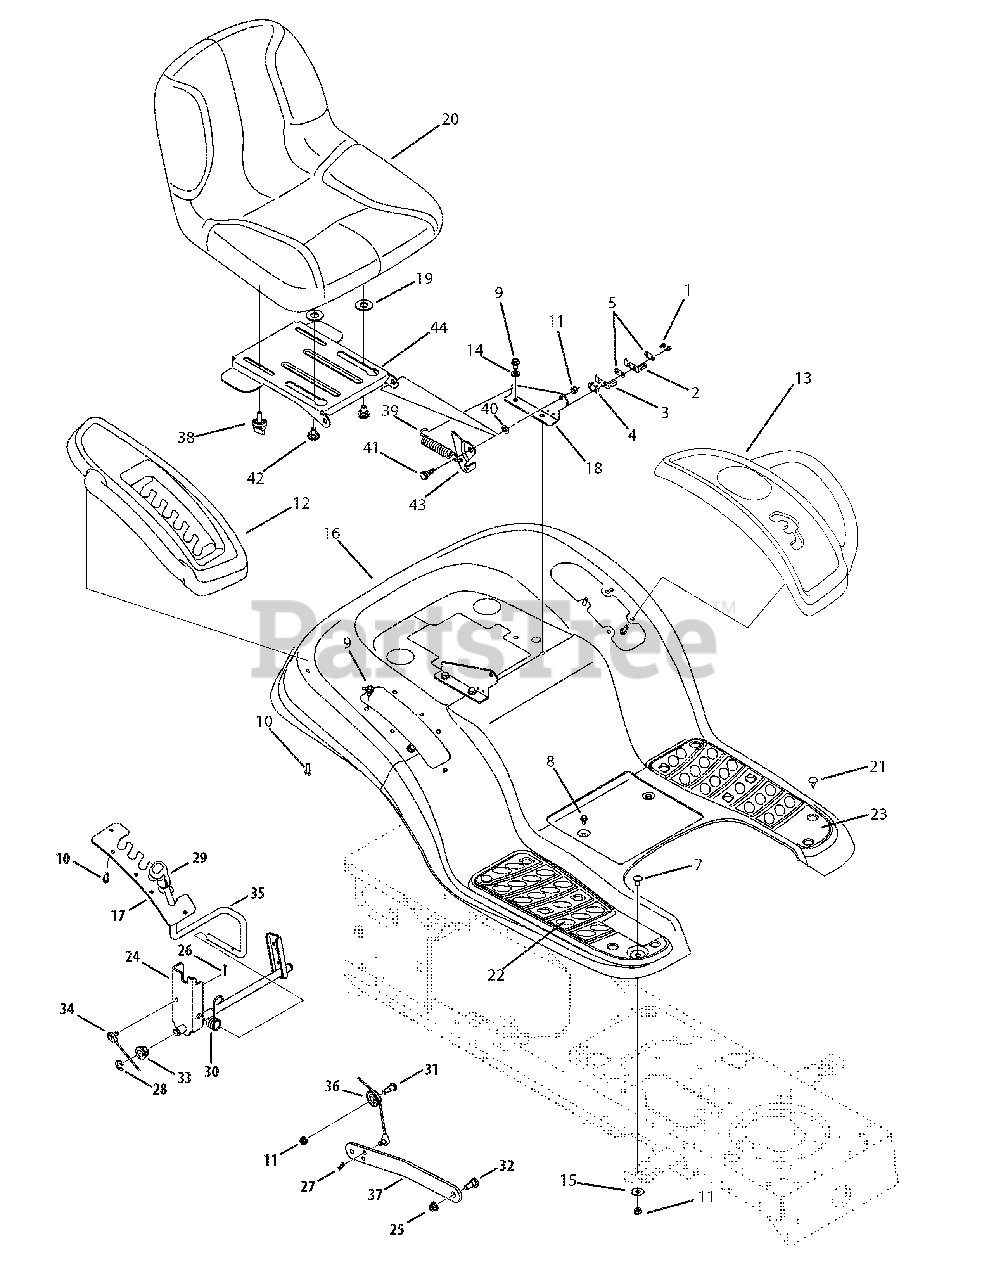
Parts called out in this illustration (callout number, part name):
1	Screw, #8-18 x.500
2	Outer Seat Spring Switch
3	Inner Seat Spring Switch
4	Insulator Boss Plate
5	Insulator Plate
6	Hex Screw, 1/4-15 x .50
7	Carriage Bolt, 5/16-18 x.750
8	Screw, 1/4-20 x.500
9	Screw, 5/16-18 x.750
10	Self-tapping Screw, 1/4-15 x.75
11	Flange Lock Nut, 5/16-18
12	LH Fender Cover
13	RH Fender Cover
14	Flat Washer, 5/16 Int. Tooth
15	Flat Washer,.349 x 1.0 x.063
19	Washer, Flat, .406 x .875 x .059
20	High Back Seat, Gray
21	Foot Pad Clips
22	RH Foot Pad
23	LH Foot Pad
26	Hairpin Clip
27	Cotter Pin
28	E-Ring
29	Handle Grip
30	Torsion Spring
31	Hex Cap Screw, 5/16-18 x.62
32	Shoulder Screw, 3/8-16
33	Hex Flange Bearing
34	Lift Cable, 16.16
35	Lift Handle
36	Roller Pulley
38	Knob, 3/8-16 x .875
39	Extension Spring,.84 x 4.6
40	Flat Washer
41	Shoulder Screw,.437 x.286
42	Shoulder Screw, 3/8-16 .625 x .145
43	Seat Lift Bracket
